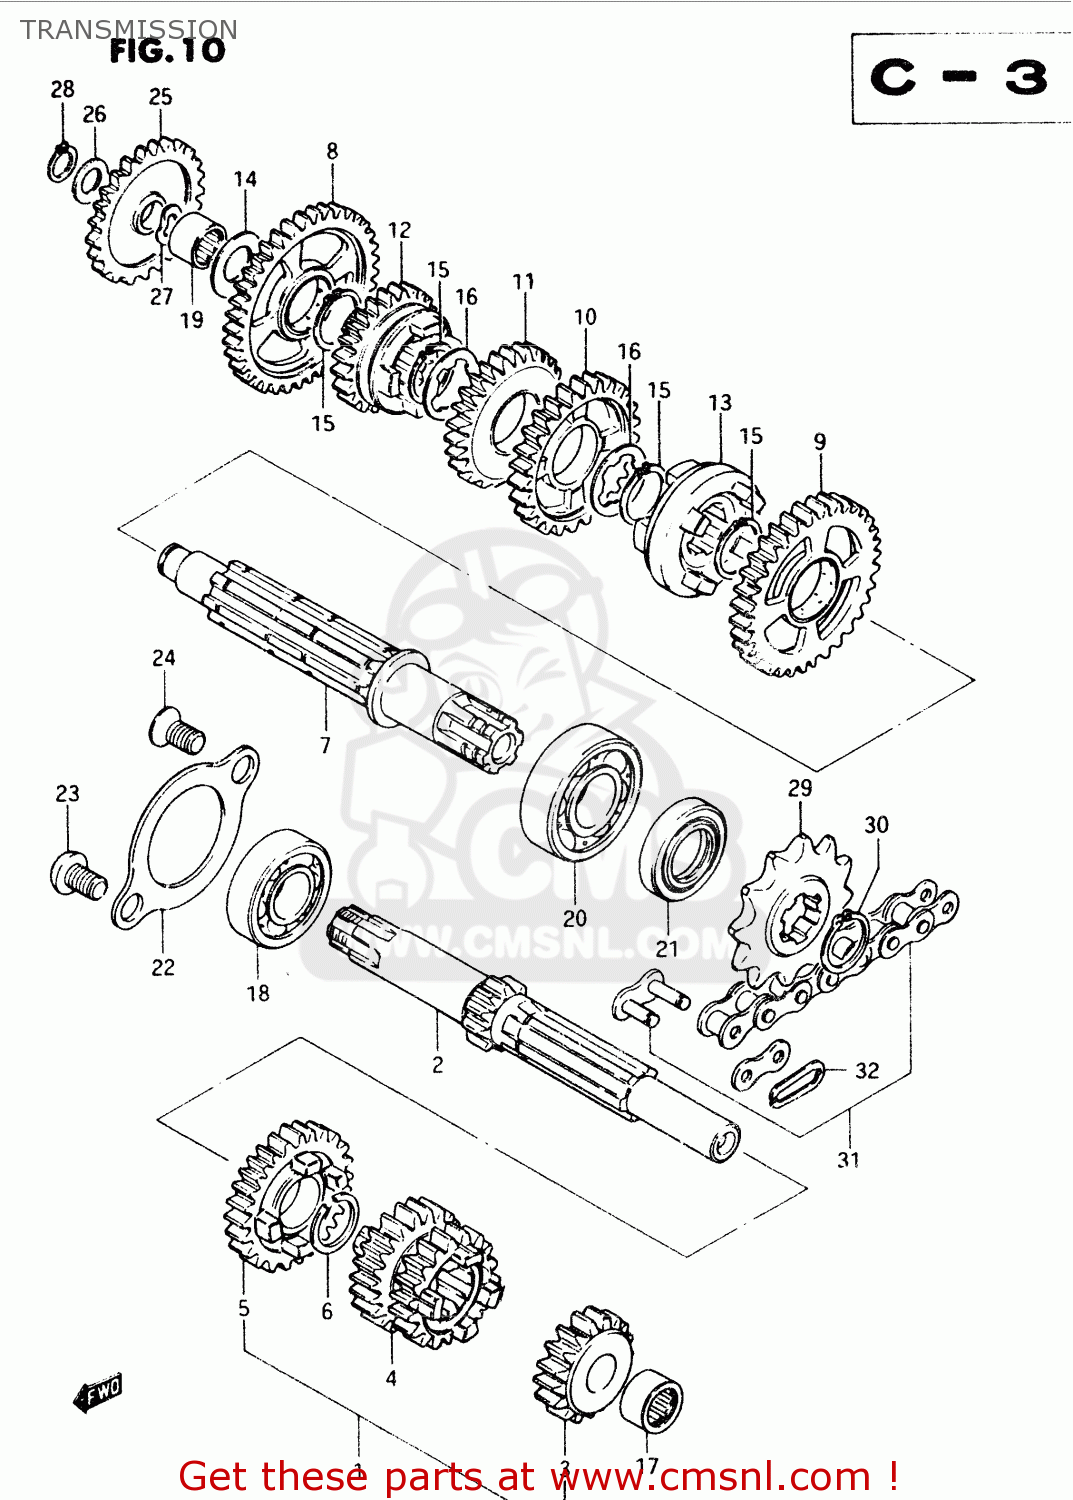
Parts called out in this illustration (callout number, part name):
1	COUNTER SHAFT ASSY
2	SHAFT,COUNTER
3	GEAR,2ND DRIVE(NT:17)
4	GEAR 3/4TH DRI
5	GEAR,5TH DRIVE
6	CIRCLIP
7	SHAFT,DRIVE
8	GEAR, 1ST DRIVEN
9	GEAR, 2ND DRIVEN (NT:33)
10	GEAR,3RD DRIVE
11	GEAR,4TH DRIVEN
12	GEAR,5TH.DRIVE
13	WHEEL, SLIDING DOG
14	RING
15	CIRCLIP
16	WASHER,LOCK
17	ROLLER BEARING (13X19X1
18	BEARING(17X40X12)
19	BEARING(15X21X12)
20	BEARING(20X47X14)
21	OIL SEAL (20X35X5)
22	RETAINER,CNTR SHAFT BEARING
23	SCREW
24	SCREW
25	GEAR,KICK STARTER IDLER(NT:26)
26	THRUST WASHER
27	WASHER
28	CIRCLIP,12 MM
29	SPROCKET,ENGIN
30	CIRCLIP
31	CHAIN ASSEMBLY,DRIVE
32	JOINT
